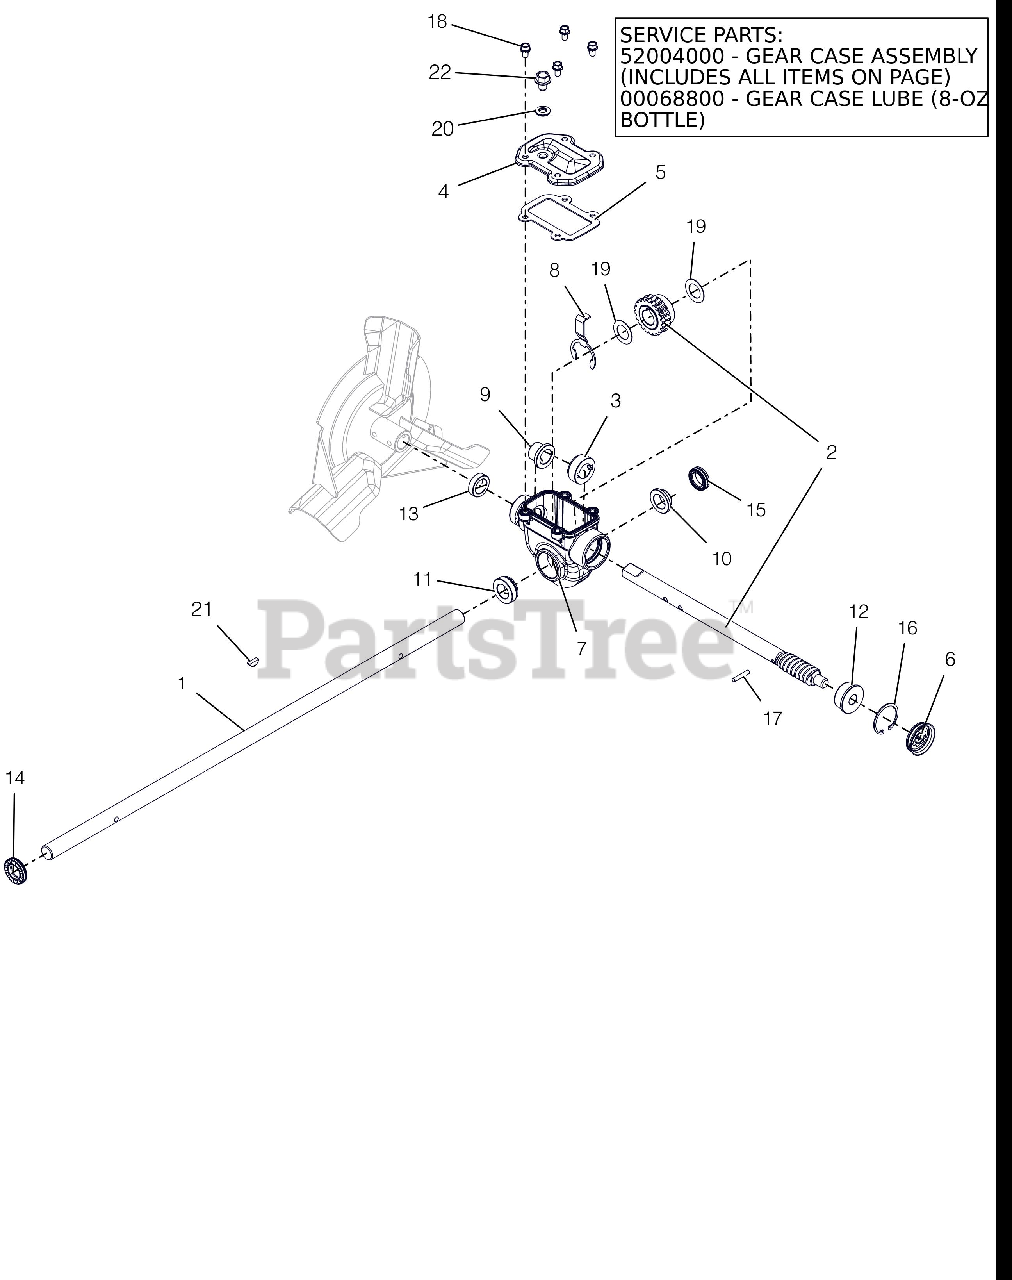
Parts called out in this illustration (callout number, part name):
1	SHAFT, RAKE-28" (.750 DIA)
2	SHAFT AND WORM GEAR ASSEMBLY
3	THRUST COLLAR, .75" ID SLIPFIT
4	COVER, TOP - COMPACT
5	GASKET, TOP - COMPACT GEARCASE
6	COVER, GEAR CASE 1.50"
7	GEARCASE, COMPACT ALUMINUM
8	BUSHING RETAINER, COMPACT
9	BSHG-FLG .755X.878X.75X1.25
10	BSHG-FLG .755X.878X.424X1.25
11	BSHG-FLG COMPACT, RIGHT
12	BSHG-FLG .503X1.303X.62X1.465
13	SEAL-OIL .748X1.125X.312 TB2-H
14	SEAL-OIL .748X1.300X.250 TBC29
15	SEAL-OIL .748X1.125X.312 TBC29
16	RG-RTNG-INT 1.500X.050
17	PIN-STR .188X1.00 6150
18	BOLT, SEMS .25-20X.50 GR5 YWZC
19	WSHR-FL-STL .760X1.225X.032 YZ
20	WSHR-BND-SEAL .38X.75X.11 GALV
21	KEY-WDRF .19X.63 HRD #61
22	@SCR-ROLOK .38-16X.50 HWH YWZC
23	GEAR CASE, 28" ALUM SM TOP-LD
23	ARIENS L3 LUBE, 8 OZ BOTTLE
